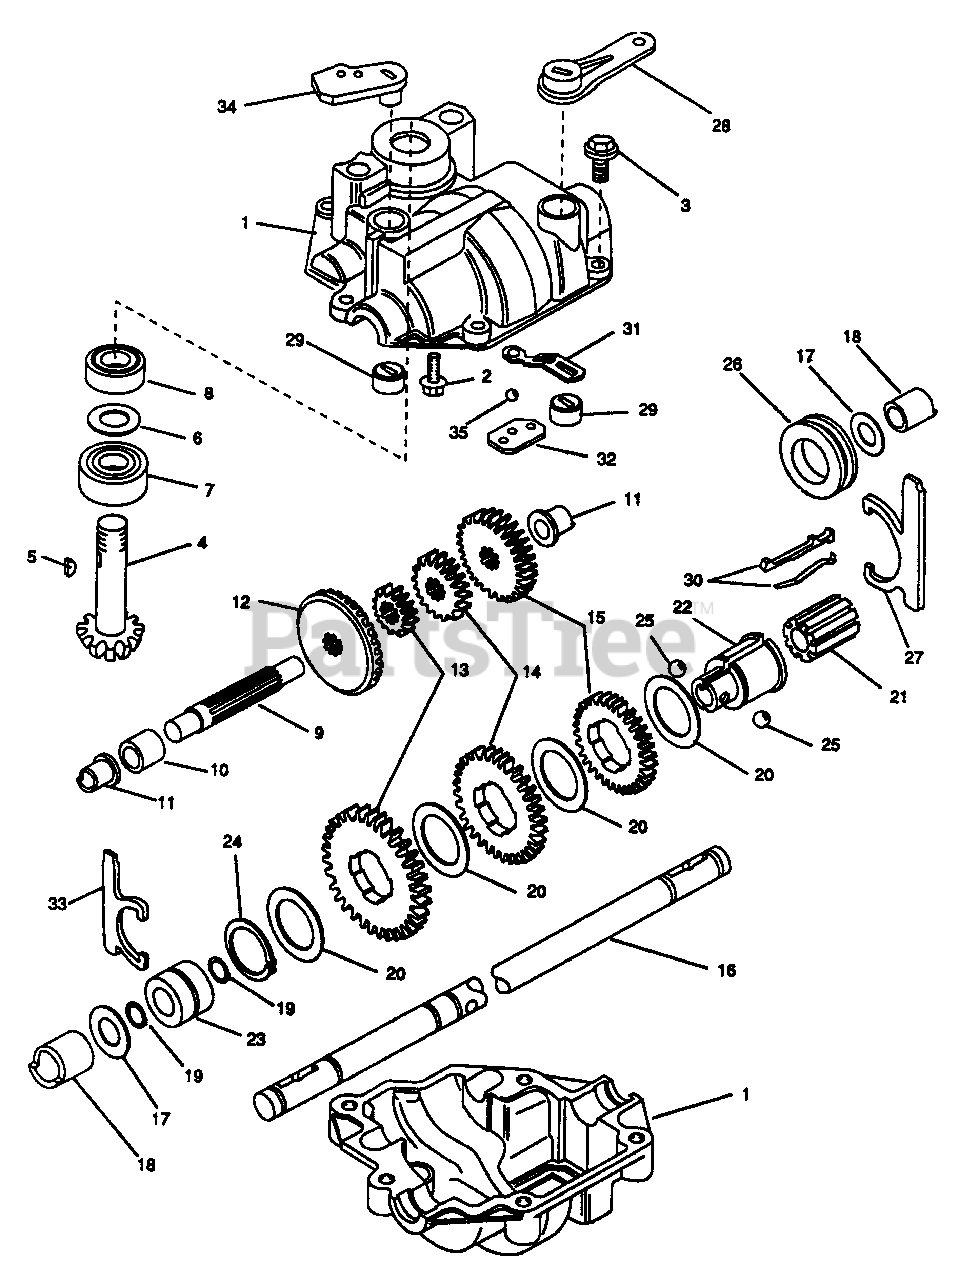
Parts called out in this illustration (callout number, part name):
1	Upper & Lower Case Kit (Inc. Sealant)
2	Tapping Screw
3	Tapping Screw
4	Shaft-Input
5	Woodruff Key
7	Bearing-Lower
8	Bearing-Upper
9	Shaft, Reduction Kit (Inc. 10-11)
11	Bushing Set
12	Ring Gear
13	Gear Set
14	Gear Set
15	Gear Set
16	Axle Shatt Kit (Inc. 17-19)
18	Bushing Set
19	Snap Ring
21	Holder, Key
22	Collar, Shift
24	Snap Ring
25	Ball
26	Collar, Sliding
27	Fork, Shift
28	Arm, Shift
29	Support, Fork
30	Spring & Key, Shift
33	Fork, Clutch
34	Arm, Clutch
